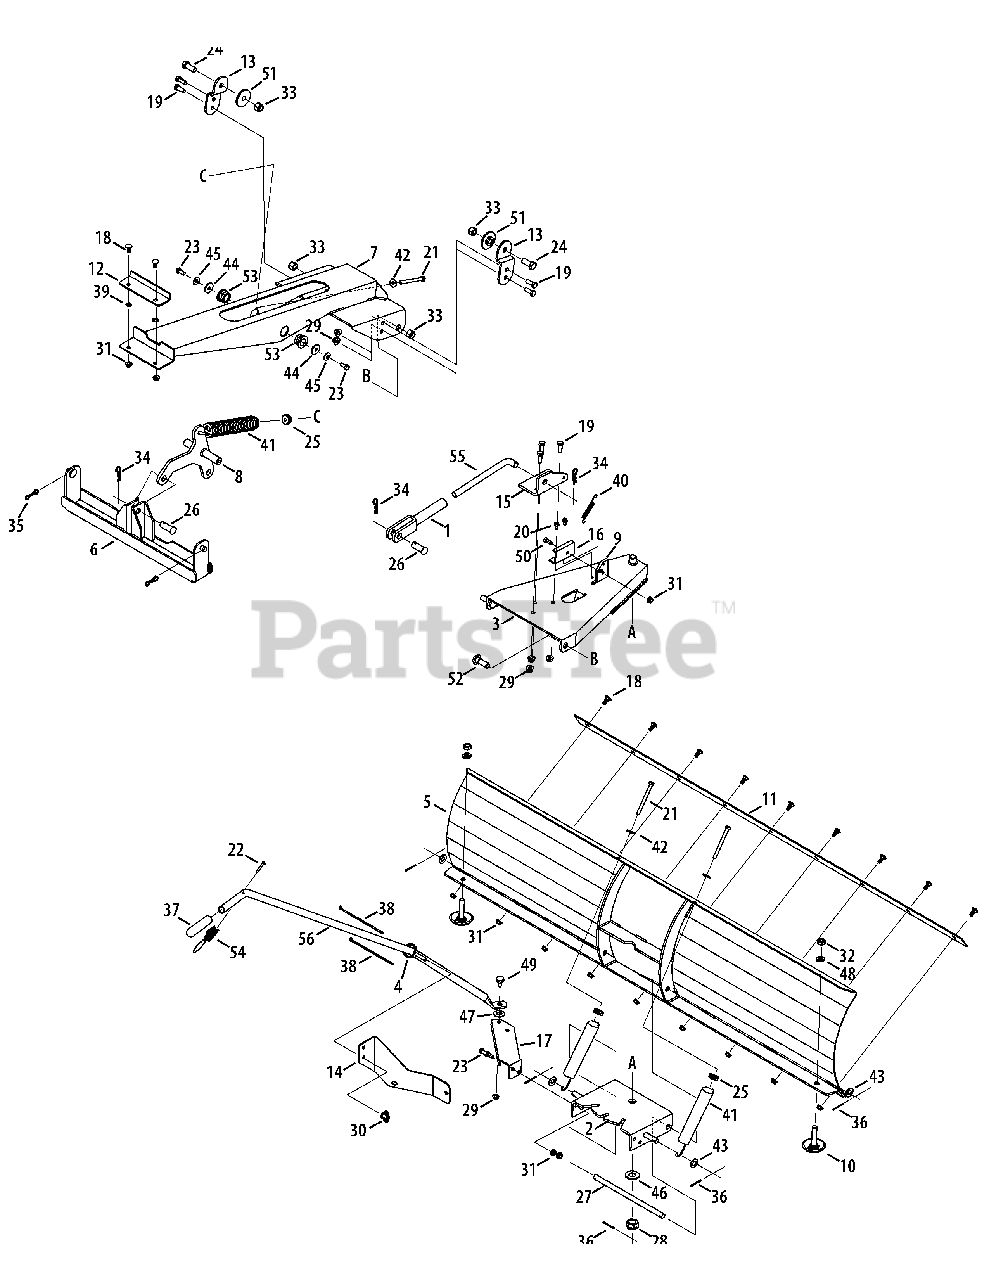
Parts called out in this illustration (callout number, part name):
1	Adjustment Clevis Assembly
3	Blade Frame Assembly
4	Eyebolt Assembly
5	Blade Assembly, 58"
6	Lift Bracket Assembly
7	Bracket Assembly
8	Pivot Bracket Assembly
9	Blade Lock Plate Assembly
10	Skid Shoe Assembly
11	Shave Plate, 46"
12	Retainer Bracket
13	Mounting Bracket
14	Handle Mounting Bracket
17	Blade Adjustment Arm
18	Carriage Bolt, 5/16-18 x .750
19	Hex Screw, 3/8-16 x 1.00
20	Hex Washer Screw, 1/4-20 x 0.500
21	Hex Screw, 5/16-18 x 3.50
22	Machine Screw, #10-24 x 1.375
23	SCREW 5/16-18 x .75 GR5
24	Hex Screw, 1/2-13 x 1.25
25	Spring Insert
26	Clevis Pin
27	Rod, .50 x 10.428
28	Slotted Nut, 3/4-16
29	Flange Lock Nut, 3/8-16
30	Nut, 5/16-18, Wing w/ Bell Washer
31	HEX FLANGE NUT
32	Jam Nut, 1/2-13
33	Nut, 1/2-13, Hex Lock Nylon
34	Cotter Pin, .125 x 1.75
35	Bow-Tie Cotter Pin
36	Cotter Pin, 1/8 x 1.25
37	Foam Grip
38	Cable Tie
39	Speed Nut, .3125 ID
40	Extension Spring, .38 x 3.25
41	Extension Spring, 1.25 x 6.7
42	Flat Washer, .349 x .879 x .063
43	Flat Washer, .530 x .930 x .050
44	Flat Washer, .344 x 1.125 x .120
45	Bell Washer, .340 x .872 x .060
46	Flat Washer, .760 x 1.50 x .120
47	Flat Washer, .570 x 1.12 x .062
48	Lock Washer, 1/2
49	SHOULDER SCREW .498 DIA x .340
50	Shoulder Screw, .405 x .435, 5/16-18
51	Shoulder Spacer, .9790 x .2025
52	Shoulder Screw, .625 x .36, 1/2-13
53	Hex Flange Bearing, .752 ID
54	Cable, Blade Release
56	Blade Adjustment Handle
